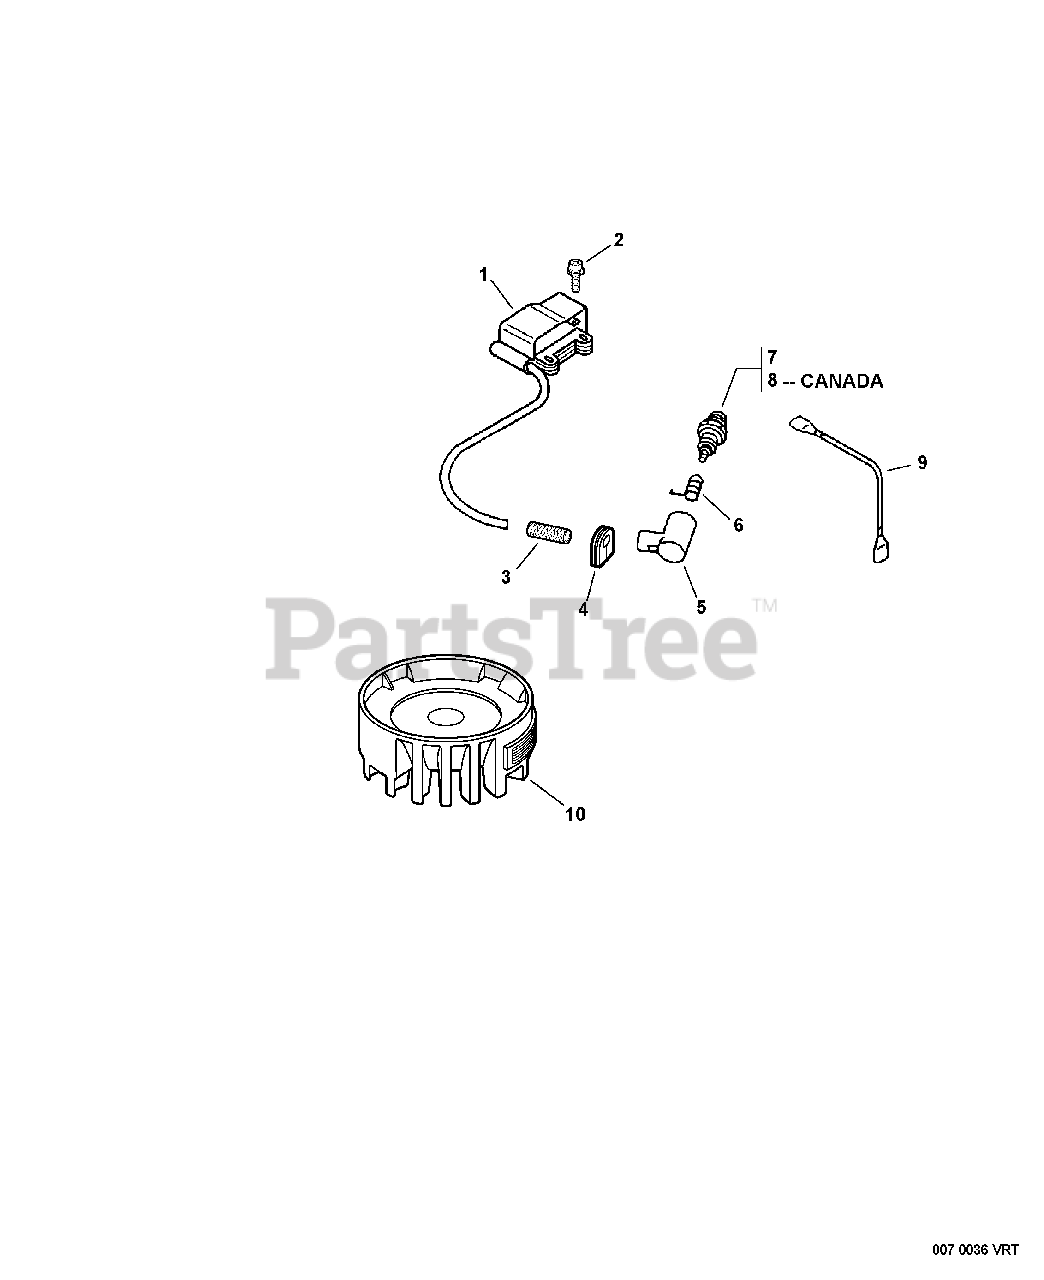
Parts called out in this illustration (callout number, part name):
1	COIL, IGNITION
2	SCREW - 4X20
3	TUBE, INSULATOR
5	CAP, SPARK PLUG
6	TERMINAL, SPARK PLUG CAP
7	SPARK PLUG -- BPM-8Y
8	SPARK PLUG -- BPMR-8Y
9	LEAD - IGNITION
10	FLYWHEEL
